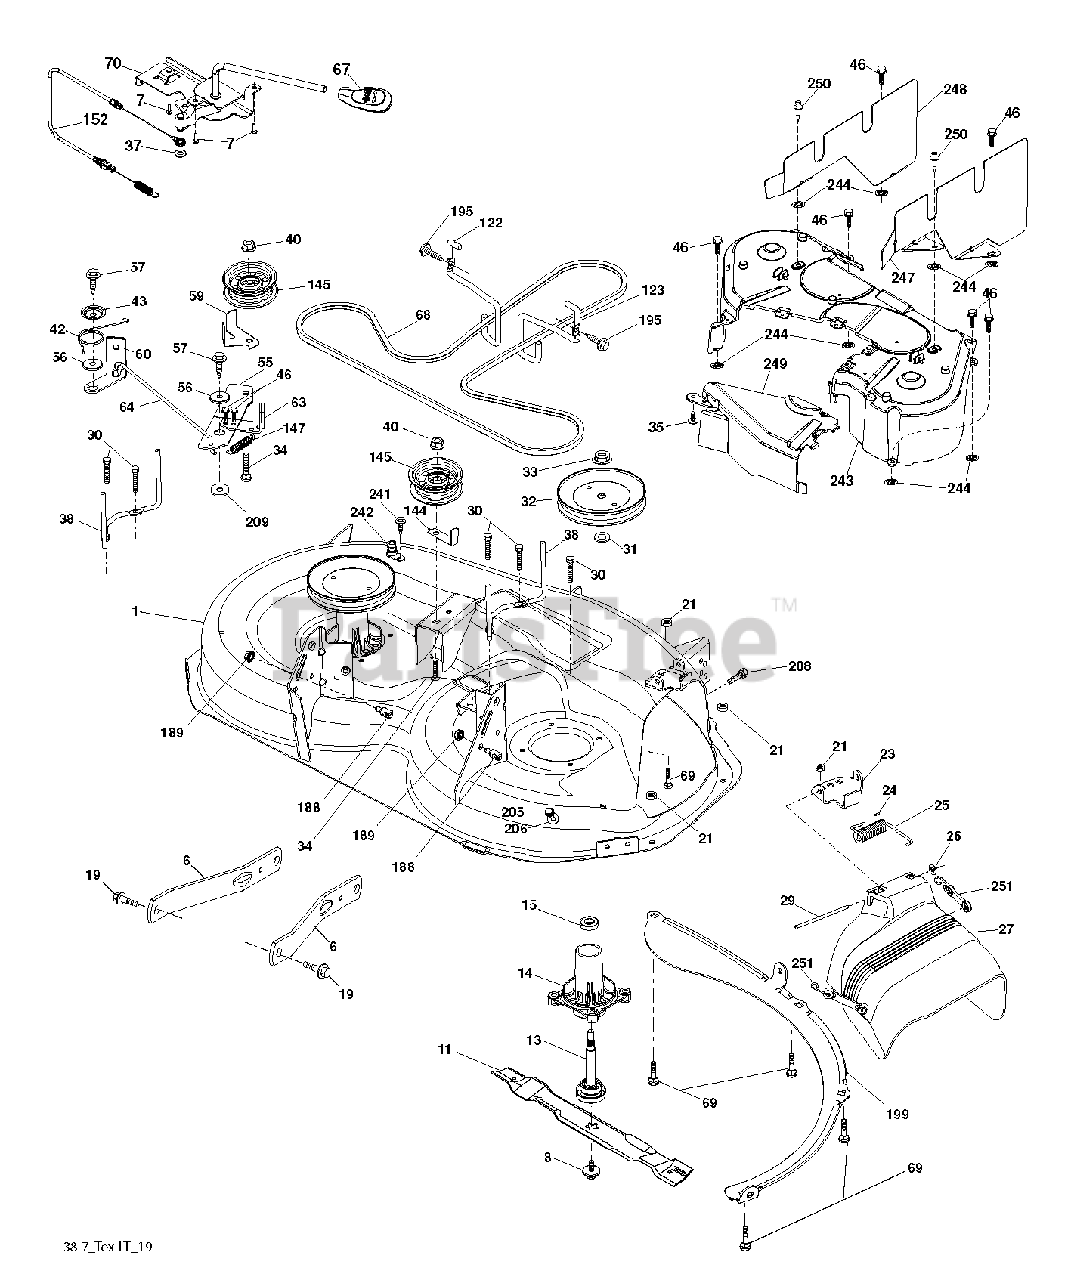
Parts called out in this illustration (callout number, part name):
6	ARM.SUSPENSION.MOWER.R
7	SCREW.#10 X 0.750.BOS THREAD
8	BOLT.WASHER.ASM.7/16-2
11	BLADE 38" PREMIUM
13	SHAFT.ASM.MDRL.N/GREASE.38
14	HOUSING MANDREL
19	BOLT.SHOULDER
21	LOCKNUT
23	BRKT.DEFLECTOR.38"2005+
24	CAP-SLEEVE LT
25	SPRING.TORSION.DEFLECT
26	NUT PUSH M
29	ROD.HINGE
30	SCREW, WASHER HEAD
31	WASHER.SPACER.MANDREL
32	PULLEY.MANDREL.5.0.PD.38"
33	NUT.FLANGE.LOCK.TOP
34	BOLT.3/8-16X1.50
35	FASTENER.XMAS.TREE
38	KEEPER BELT LH MANDREL
40	NUT LOCK FLG 3/8-16 UNC
42	SPRING.TORSION.BRAKE
43	SRPING.TORSION.RETAINE
46	SCREW.1/4-20X5/8
55	IDLER.ARM
56	SPACER.RETAINER
57	SCREW 3/8-16X1
59	GUARD, BELT
60	ARM BRAKE MOWER RH 38"
63	ARM BRAKE MOWER RH
64	LINK BRAKE
67	HANDLE.CLUTCH.CABLE.LT
69	BOLT
70	CLUTCH.ASM.MANUAL.LT.PRED
122	KEEPER BELT ENGINE LH
123	KEEPER BELT RH
144	KEEPER BELT
145	PULLEY.IDLER.48"PRIMARY
147	SPRING RETURN
152	CABLE.CLUTCH.MANUAL.
188	STUD.FASTNER.W/ANTI-ROTATE
189	NUT LOCK HEX FLANGE 5/16-18
195	SCREW, 3/8-16X3/4
199	BAFFLE VORTEX
205	SCREW
208	SCREW 3/8-16X1/2
209	WASHER 12/32X2X10GA
242	PORT.WASHOUT
244	PALNUT 1/4
